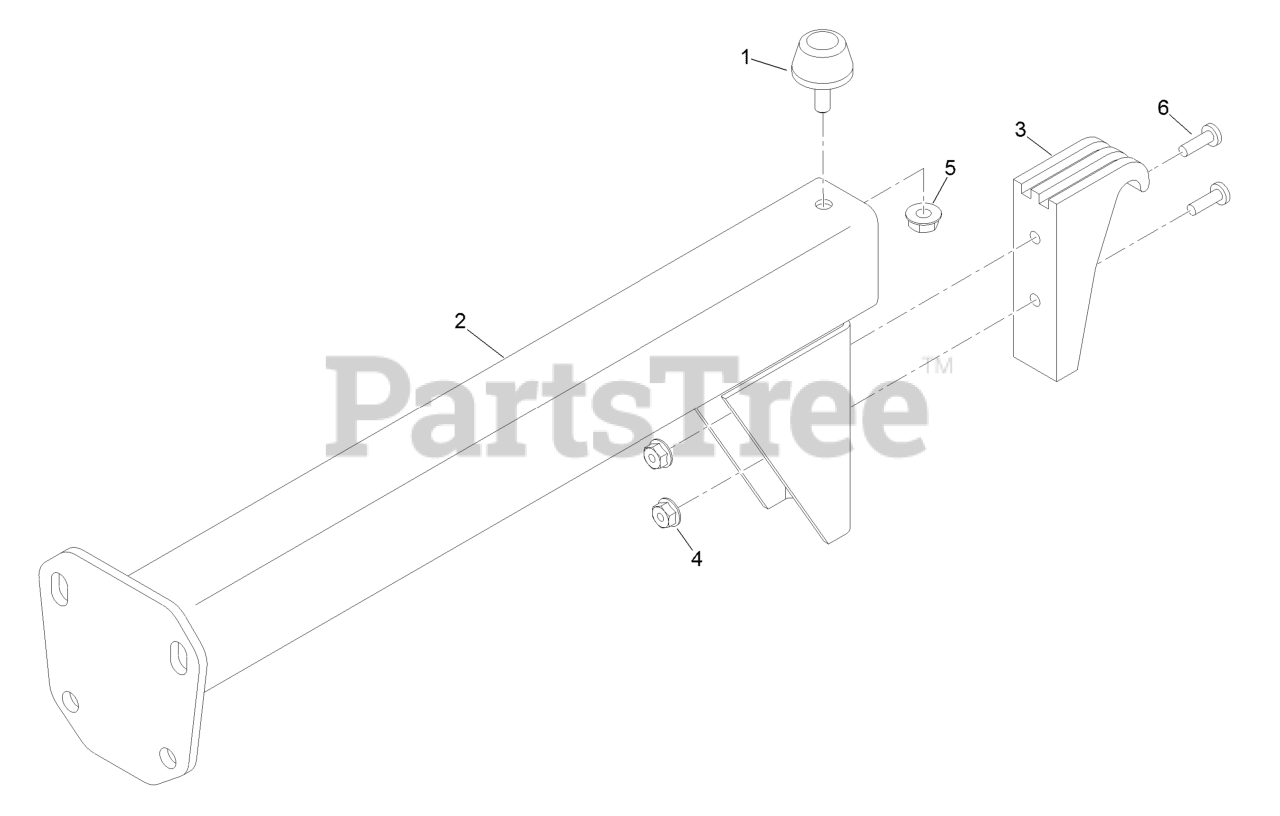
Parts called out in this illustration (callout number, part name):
2	Support-Bag
4	Nut-Whizlock
5	Nut-Whizlock
6	Screw-PPH
